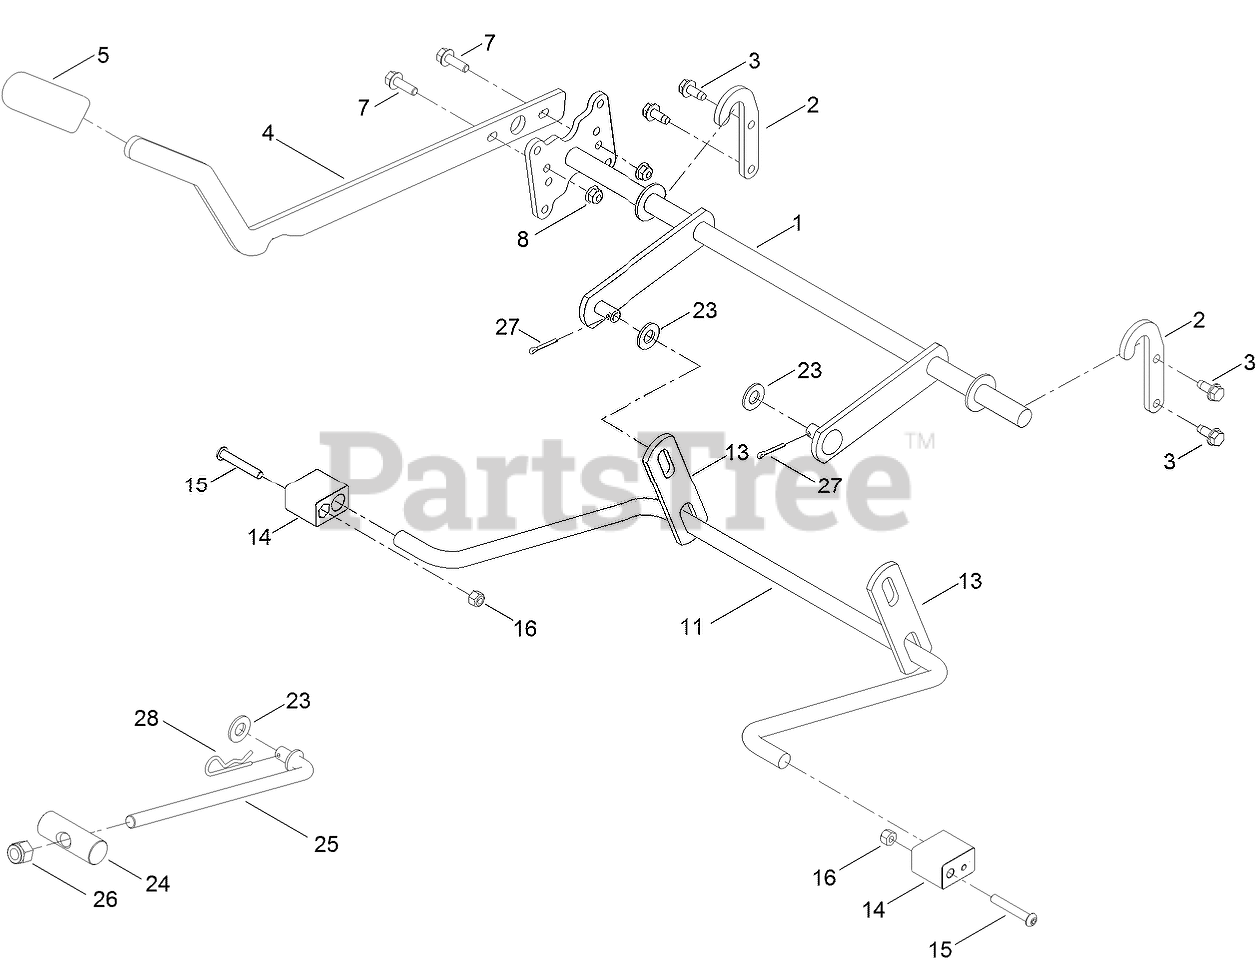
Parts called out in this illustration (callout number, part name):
1	LIFT-DECK, NARROW
2	BRACKET-LIFT
3	SCREW-HWHTF
4	LEVER-LIFT
5	GRIP-LEVER
7	SCREW-HHF
8	NUT-HF, NI
11	ARM-LIFT, REAR
13	LINK-LIFT
14	BLOCK-PIVOT
15	SCREW-HSBH
16	NUT-LOCK, NI
23	WASHER-FLAT
24	PIN-PIVOT
25	ROD-MOUNT, DECK
26	NUT-HEX
27	PIN-COTTER
28	PIN-COTTER
